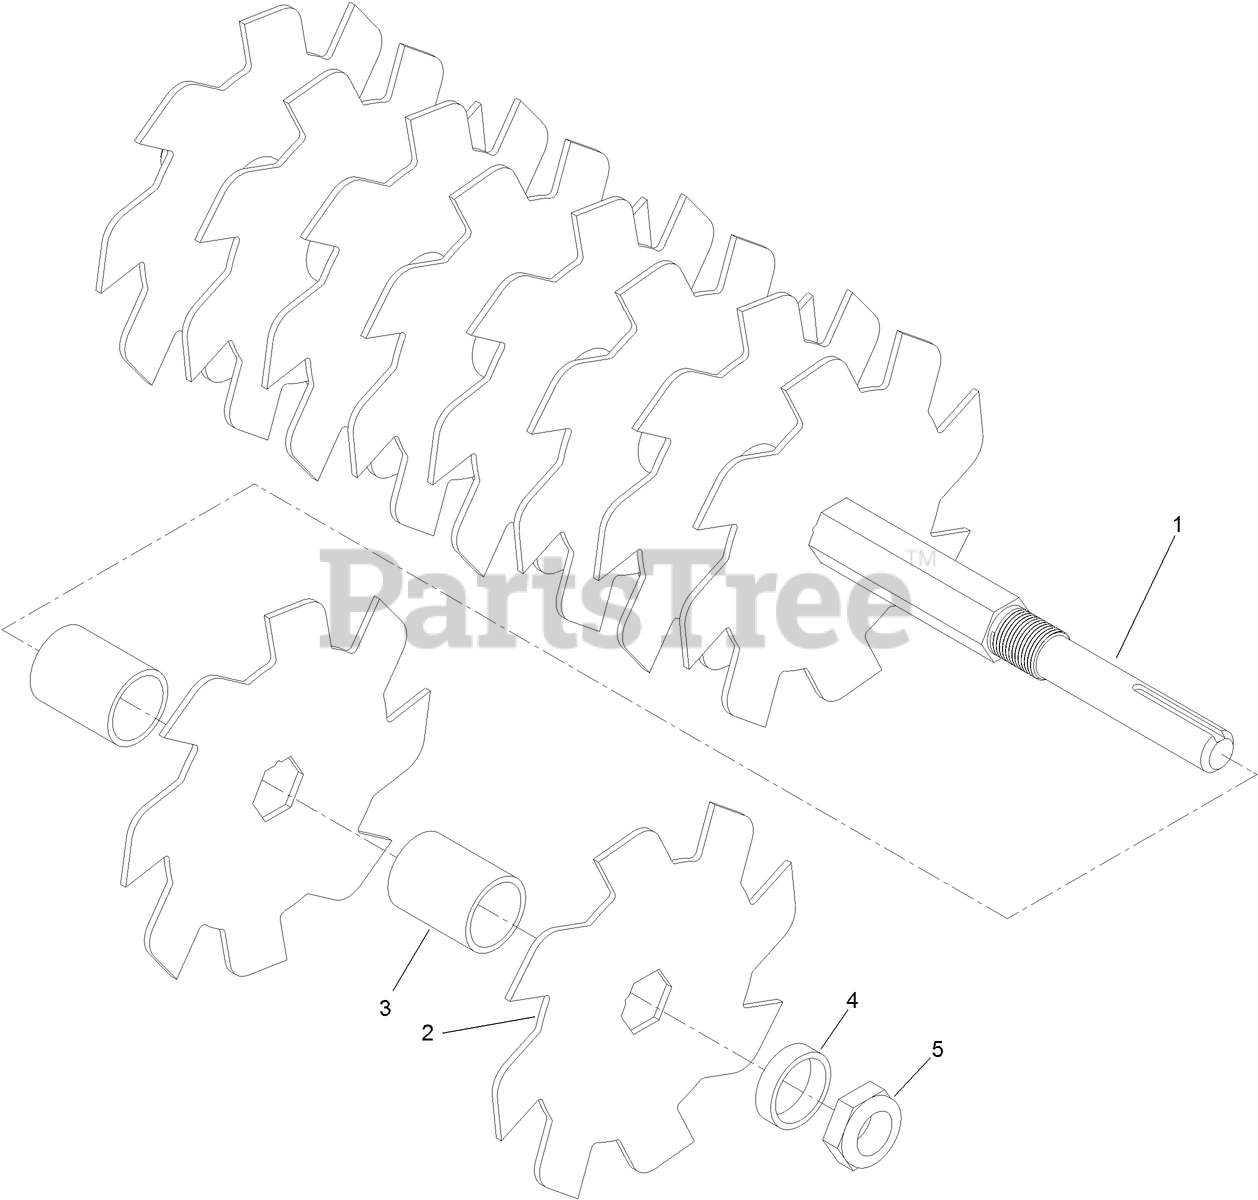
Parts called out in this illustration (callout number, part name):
1	SHAFT-SLICER
2	BLADE-CUTTING, SEEDER
3	SPACER-BLADE
4	SPACER
5	NUT-LOCK, NI
